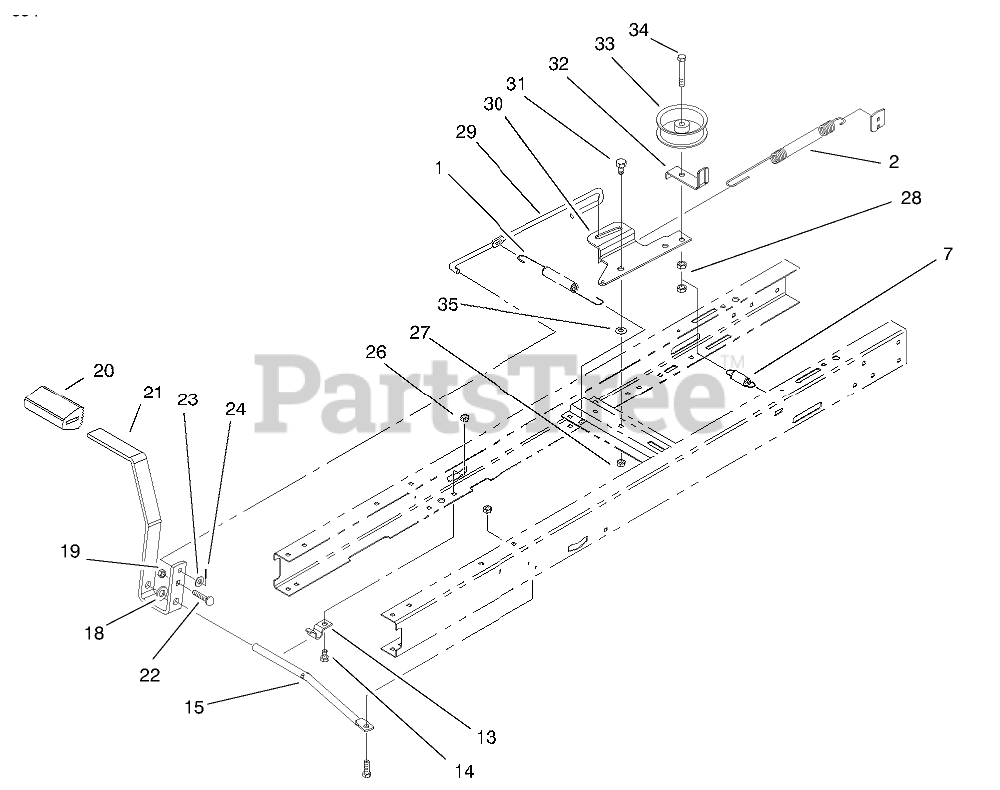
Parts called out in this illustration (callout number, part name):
1	SPRING-EXTENSION
2	BRAKE SPRING
7	SPRING-EXTENSION
13	CLAMP-PIVOT, SHIFT
14	SCREW-HH
15	ROD-PIVOT, PEDAL
18	WASHER-FLAT
19	NUT-LOCK, NI
20	PAD-PEDAL
21	PEDAL-CLUTCH/BRAKE, HYDRO
22	SCREW-CARR
23	WASHER-PLAIN
24	PIN-COTTER
26	NUT-LOCK, NI
27	NUT-LOCK, NI
28	NUT-LOCK, NI
29	ROD-CLUTCH/BRAKE
30	ARM-IDLER
31	BOLT-SHOULDER
32	GUIDE-IDLER, BELT
33	Idler Pulley
34	SCREW-HH
35	WASHER-PIVOT
